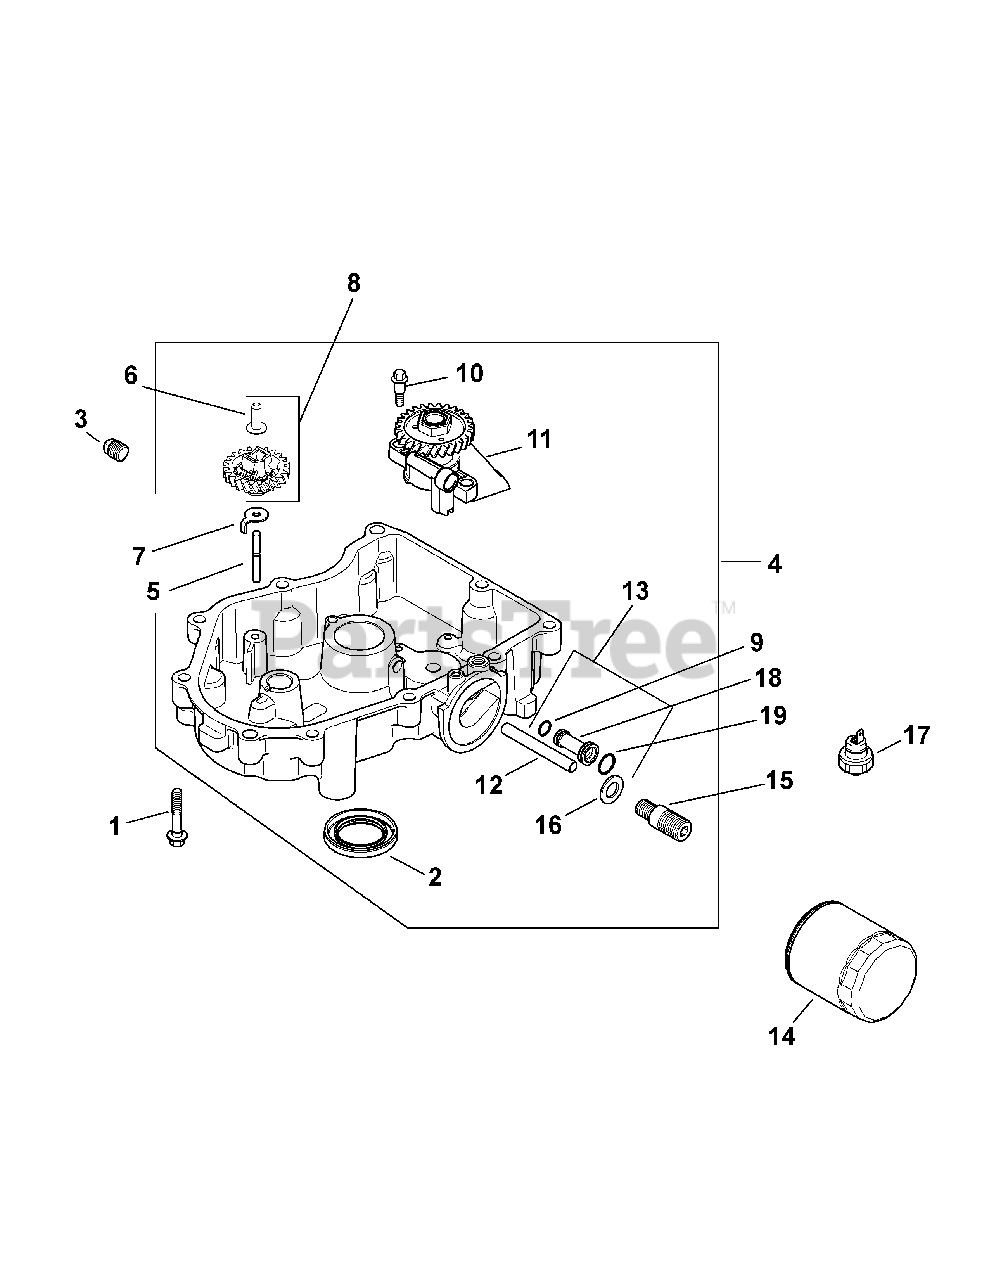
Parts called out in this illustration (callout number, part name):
1	Flange Screw, M8 x 1.25 x 45
2	Oil Seal, 2.38 x 1.45
3	Square Head Pipe Plug, 3/8
4	Oil Pan Assembly
5	Governor Gear Shaft
6	Governor Regulating Pin
8	Governor Gear Kit
9	Oil Pick-Up O-Ring
11	Oil Pump Assembly
12	Oil Feed Tube (Filter to Oil Pan)
13	Oil Feed Tube Assembly
15	Oil Filter Nipple
17	Oil Pressure Switch
18	Oil Feed Tube
